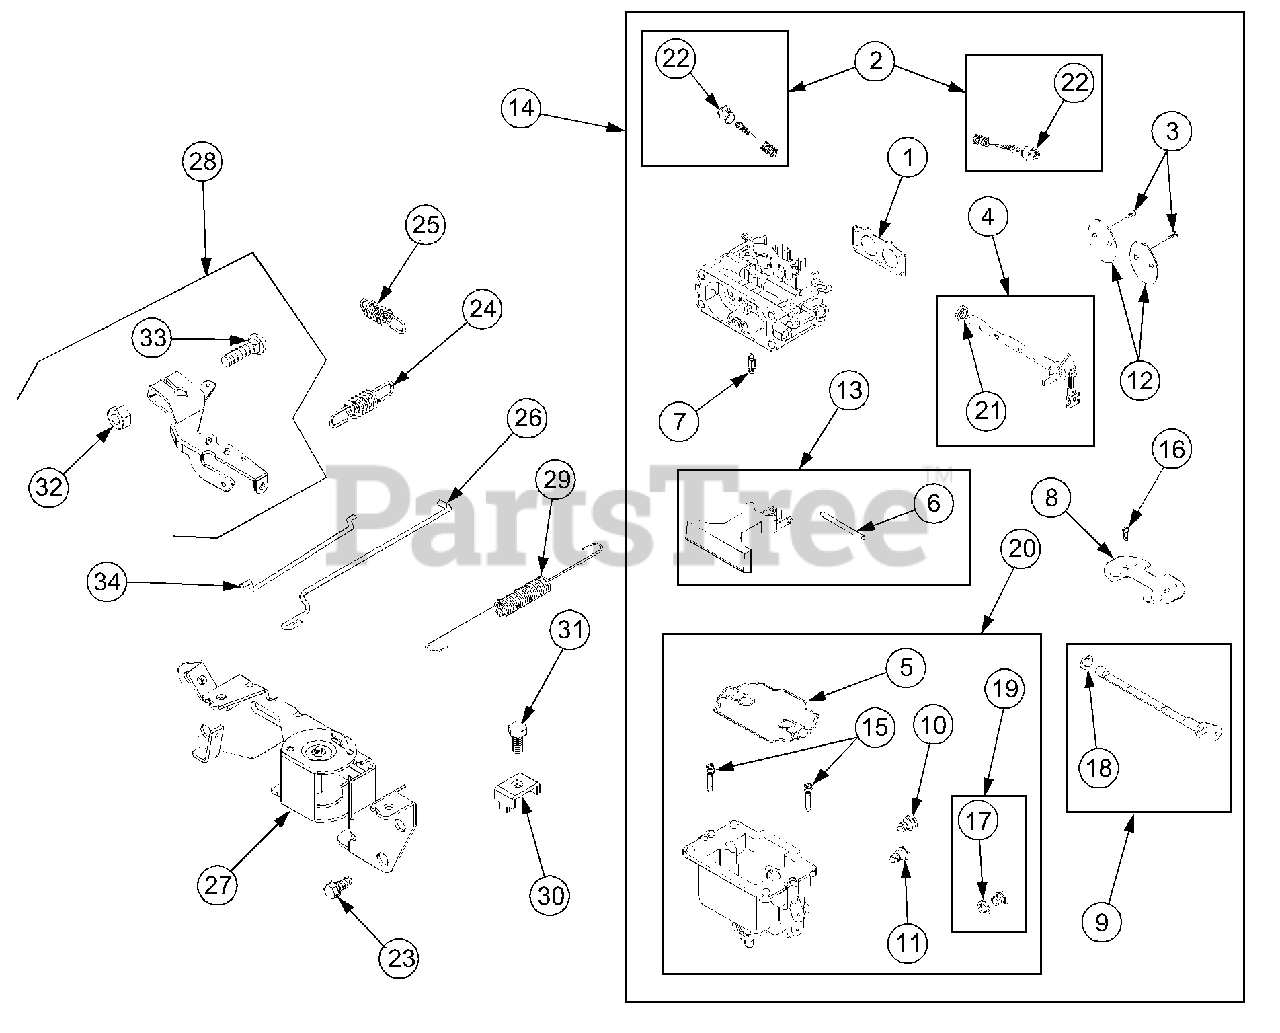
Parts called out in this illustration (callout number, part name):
1	Gasket, Intake
2	Kit, Idle Mixture
3	Screw, Throttle Valve
4	Shaft, Throttle
5	Gasket, Carburetor Body
6	Pin, Float Hinge
7	Valve, Float Needle
8	Valve, Choke
9	Shaft, Choke
10	Jet, Main (Standard) - Cylinder #1
11	Jet, Main (Standard) - Cylinder #2
12	Valve, Throttle
13	Float, Carburetor
14	Carburetor
15	Nozzle, Carburetor
17	Washer, Sealing
18	Seal, Choke/Throttle Shaft
19	Plug, Carburetor
20	Bowl, Float
21	Seal, Throttle Shaft
22	Cap, Limiter
24	Spring, Governor
25	Spring, Governed Idle
26	Link, Throttle
27	Bracket, Control
28	Lever, Governor Control
29	Spring, Governor Link
30	Clamp, Casing
32	Nut, Governor Control Lever
33	Bolt, Governor Control Lever
34	Link, Choke
